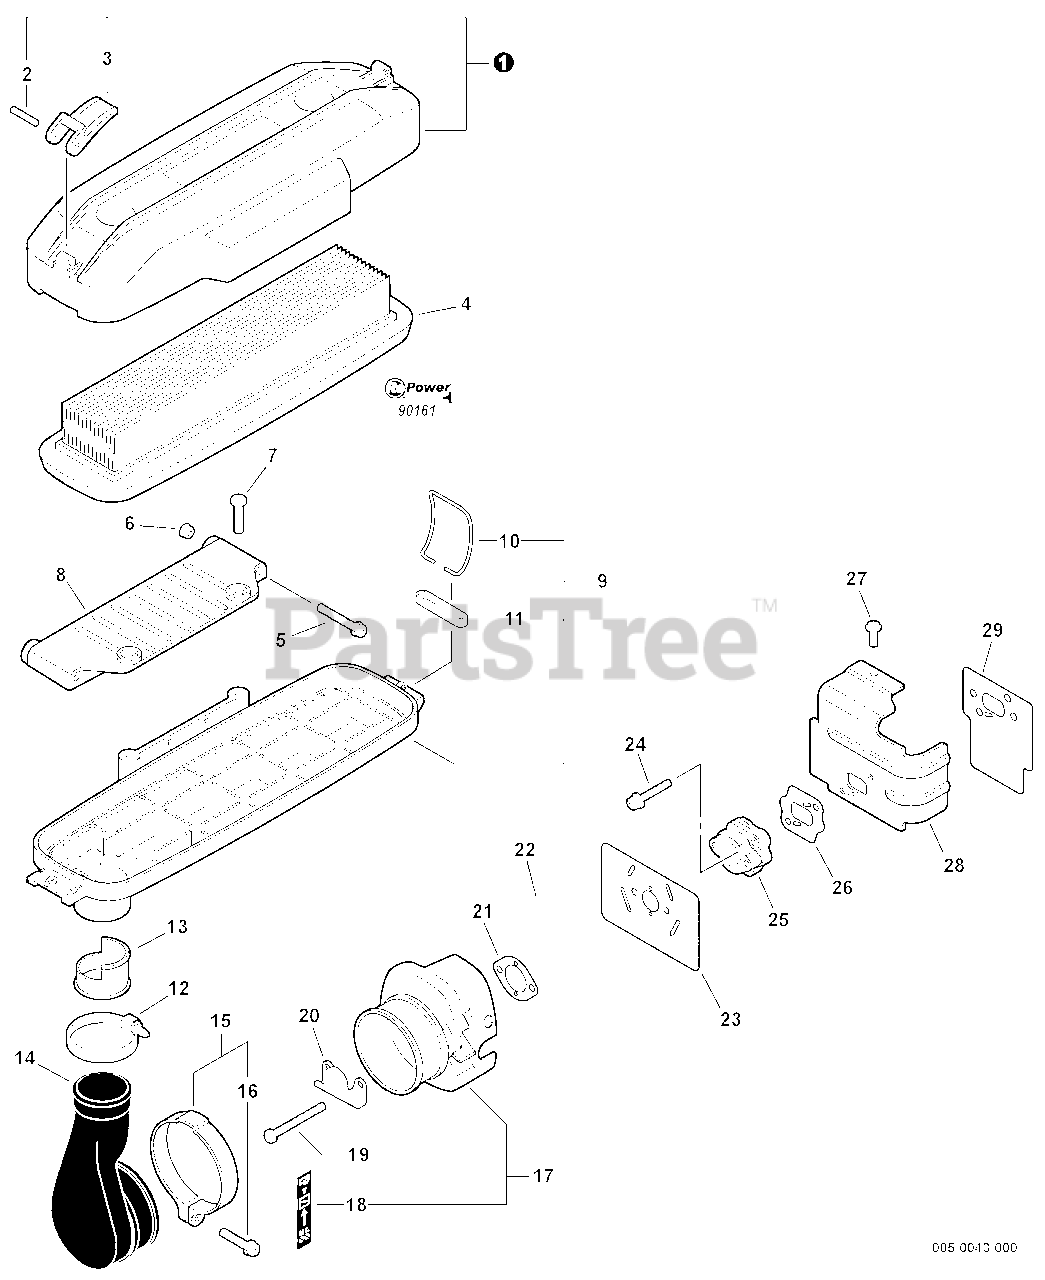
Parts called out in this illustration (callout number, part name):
1	COVER ASSY, AIR FILTER
2	PIN, SPRING 3×25
4	FILTER, AIR
5	SCREW 5×40
6	NUT, FLANGE M5
8	BRACKET
9	AIR FILTER CASE ASSY
13	COLLAR 27
14	ADAPTOR, INTAKE
15	CLAMP KIT
16	SCREW 5×25
17	BRACKET KIT, AIR FILTER
18	LABEL, CHOKE
19	BOLT 5×60
20	PLATE, PREVENT
21	GASKET, INTAKE
22	CARBURETOR
23	GASKET, INTAKE
24	BOLT 5×25
25	INSULATOR, INTAKE
26	GASKET, INTAKE
27	SCREW 5×10
28	COVER, CYLINDER
29	HEAT SHIELD, INTAKE
30	TUNE-UP KIT - REPOWER
